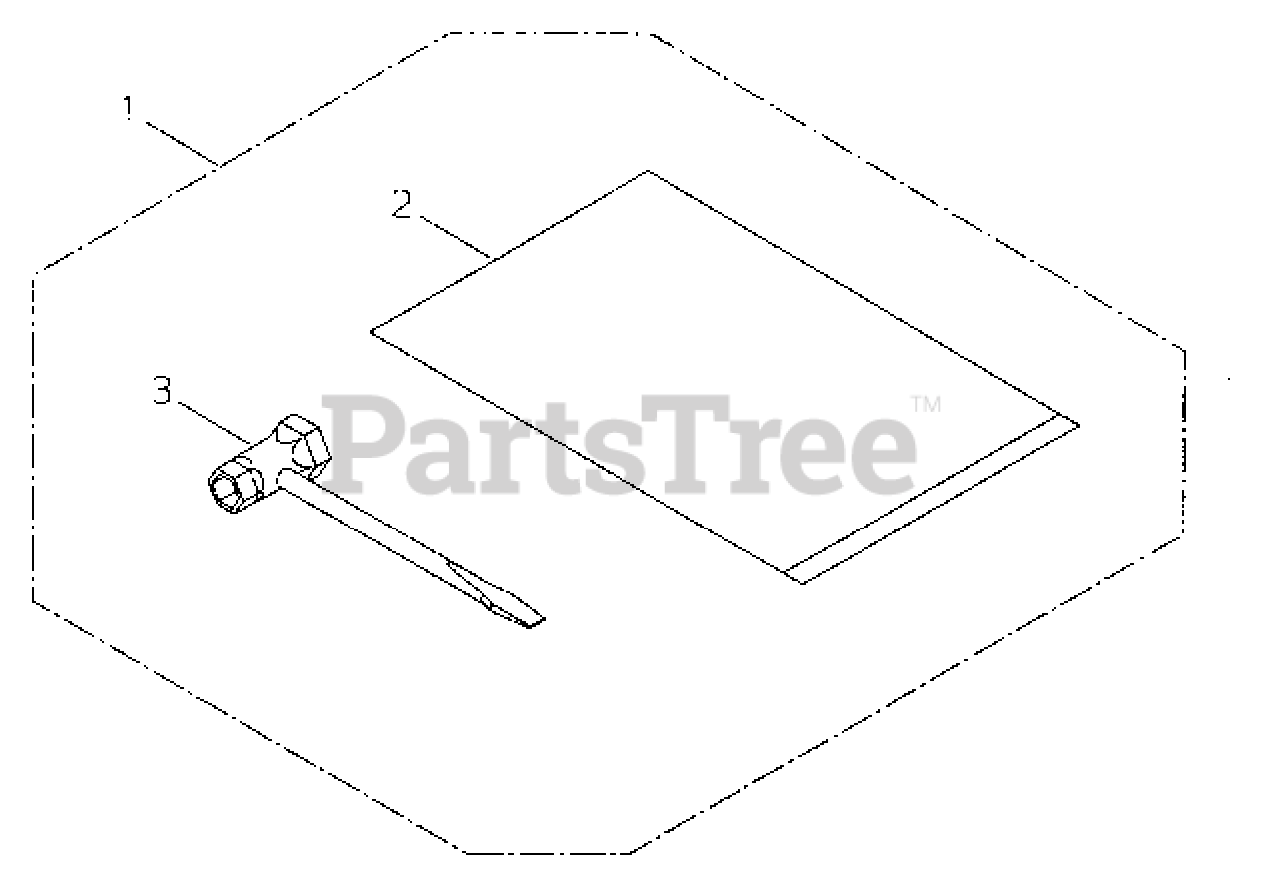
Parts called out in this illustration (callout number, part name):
1	TOOL KIT
2	BAG, TOOL
3	T-WRENCH
